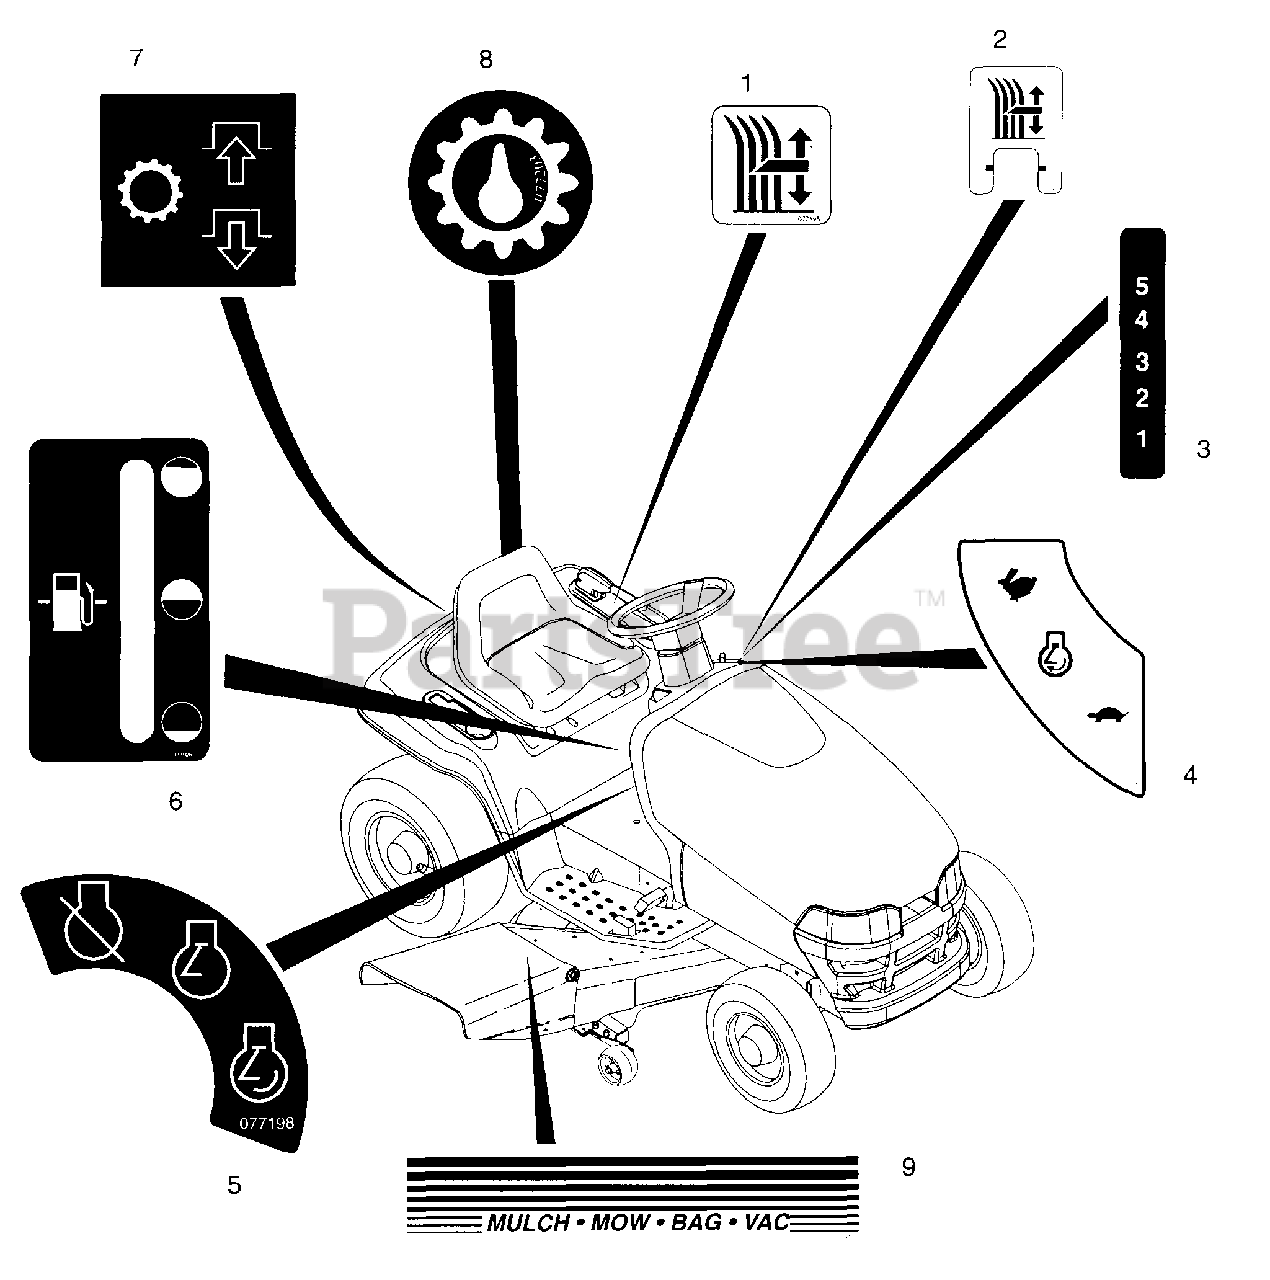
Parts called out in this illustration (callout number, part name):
1	DECAL - CUT HEIGHT - INSERT
2	DECAL - CUT HEIGHT - FRAME
3	DECAL - INDICATOR 5 POS
4	DECAL- THROTTLE W/O CHOKE
5	DECAL - IGNITION
6	DECAL- FUEL LEVEL
7	DECAL-TRANS. DISCONNECT
8	DECAL-OIL RESERVOIR
9	DECAL- MULCH-MOW-BAG-VAC
